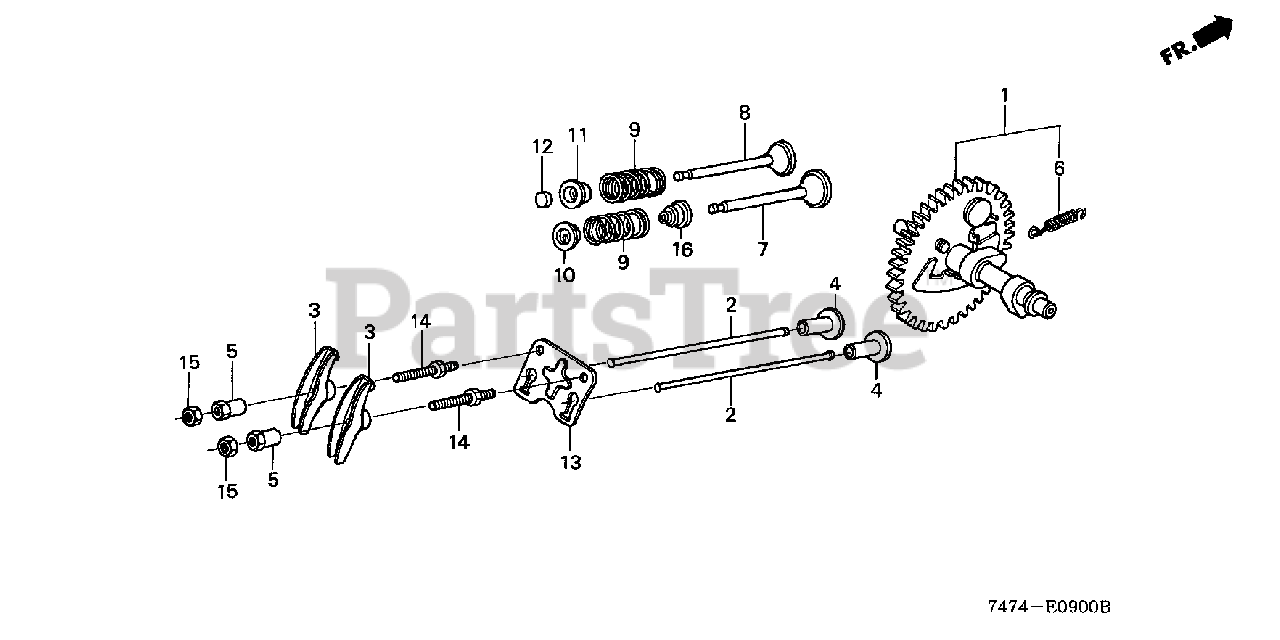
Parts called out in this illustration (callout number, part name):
1	CAMSHAFT ASSY.
2	ROD, PUSH
3	ARM, VALVE ROCKER
4	LIFTER, VALVE
5	PIVOT, ROCKER ARM
6	SPRING, WEIGHT RETURN
7	VALVE, IN.
8	VALVE, EX.
9	SPRING, VALVE
10	RETAINER, IN. VALVE SPRING
11	RETAINER, EX. VALVE SPRING
12	ROTATOR, VALVE
13	PLATE, PUSH ROD GUIDE
14	BOLT, PIVOT (8MM)
15	NUT, PIVOT ADJ.
16	SEAL, VALVE STEM
